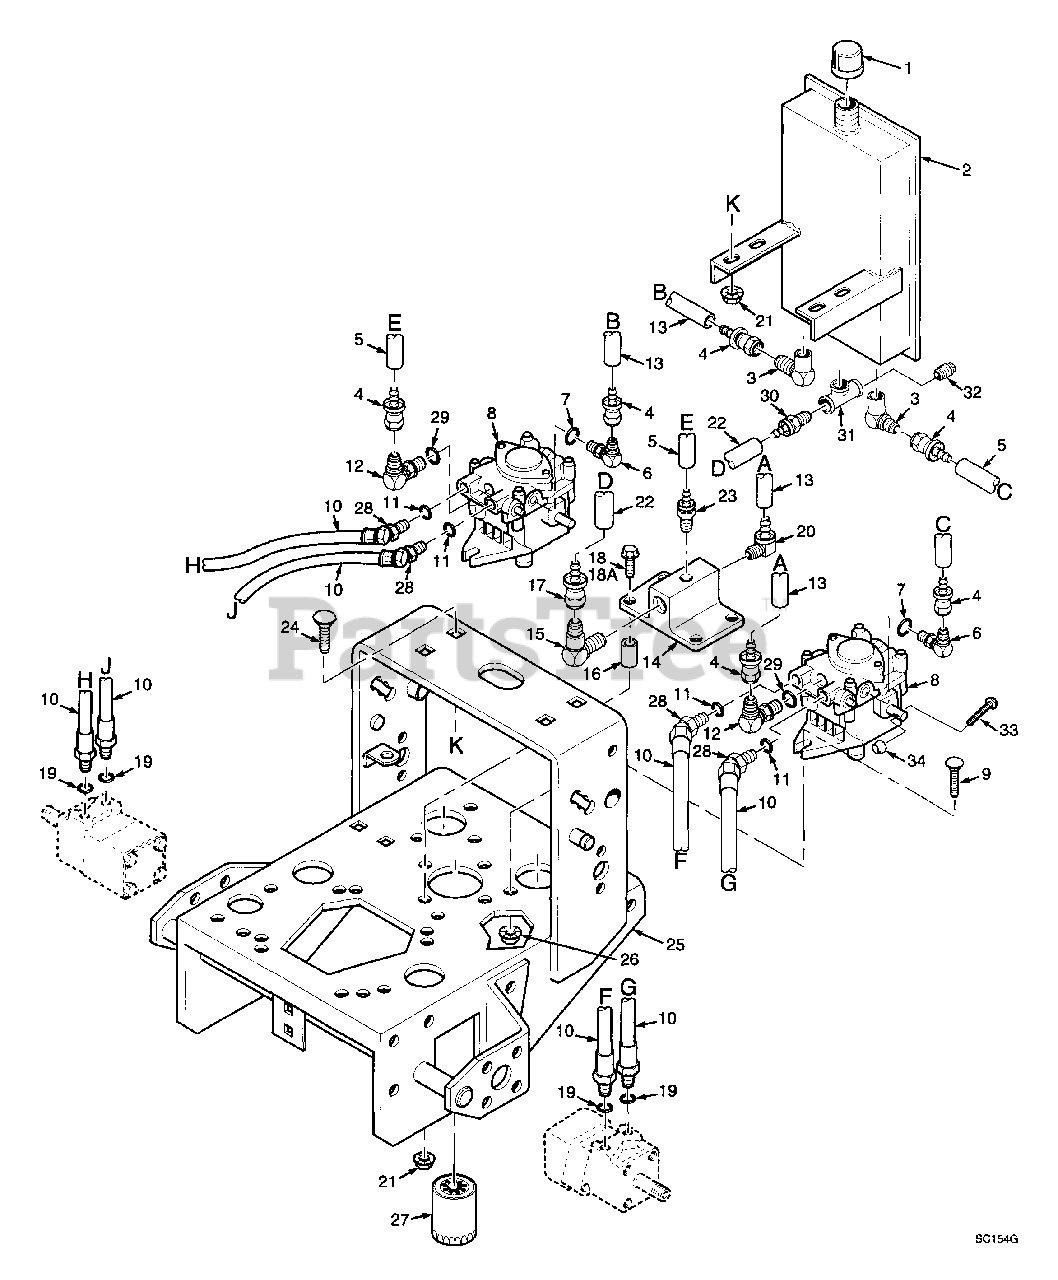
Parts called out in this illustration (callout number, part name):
1	Cap, Oil Reservoir
2	Oil Reservoir
3	Elbow, 90ø Female 1/4 NPT to 1/4 JIC Male
4	Coupling, 7/16-20 SAE Flare Swivel to 1/4" Hose Push On
5	Hose, 1/4" ID - 12" Long
6	Elbow, 90ø 7/16-20 JIC to 9/16-18 "O" Ring
7	O-Ring
8	Pump, Sunstrand BDP-10L117
9	Bolt, Carriage, 3/8-16 x 1-1/4
10	Hose, Pump to Motor
11	O-Ring
12	Elbow, 90ø, 7/16-20 JIC x 7/16-20 O-Ring
13	Hose, 1/4" ID - 10" Long
14	Oil Filter Base
15	Elbow, 90ø Male 3/4-16 JIC to 1/2" Male NPT
16	Spacer, Oil Filter Base
17	Coupling, 3/4-16 SAE Flare Swivel to 1/2" Hose Push On
18	Capscrew, 5/16-18 x 2.25" (For 20") Serr. Flange
19	O-Ring
20	Elbow, 90ø Male 1/4 NPT to 1/4 Hose Push On
21	Nut, 5/16-18 Serr. Flange
22	Hose, 1/2" ID, 12" Long
23	Coupling, 1/4 straight Male NPT to 1/4 Hose Push On
24	Bolt, 5/16-18 x 3/4" Carriage
25	Engine Deck (20" Wide) W/ Decals
26	Nut, 3/8-16 Serr Flange
27	Oil Filter
28	Elbow, 45ø - 3/4-16 JIC Male x Male 3/4-16 O-Ring
29	O-Ring
30	Coupling, 3/8 Straight Male NPT to 1/2 Push-on
31	T-Fitting, 3/8 NPT
32	Plug, 3/8-18 NPTF Magnetic
33	Screw, 1/4-20 x 2.0" Round Head Phillips
34	Nut, 1/4-20 Elastic Stop
